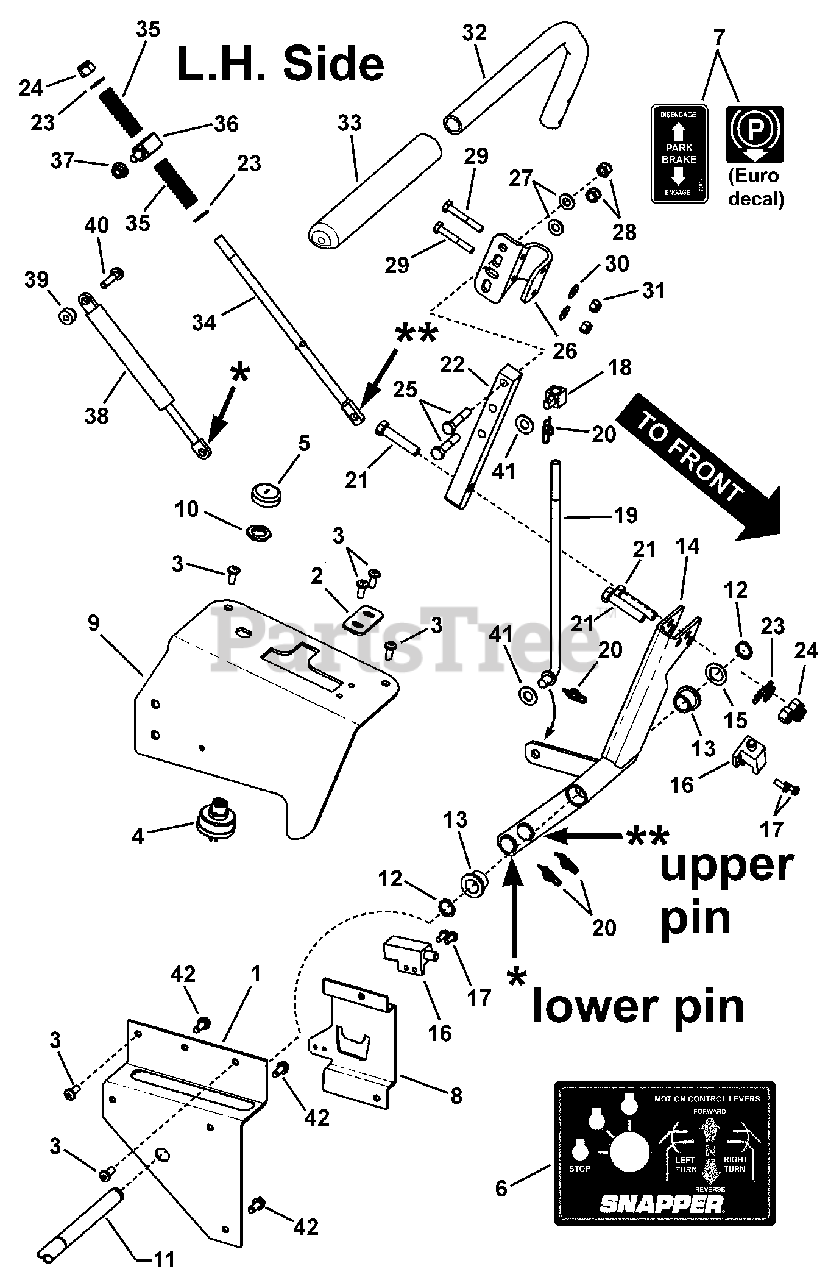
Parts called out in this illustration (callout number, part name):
1	BRACKET, L.H. Tank Support
2	BRACKET, Speed Adjustment
3	SCREW, 1/4-20 x 5/8" Pan Head Self-Tap (Torx)
4	SWITCH, Ignition (After-fire Solenoid)
5	BEZEL
6	DECAL, Ignition Switch
7	DECAL, Park Brake
8	BRACKET, Brake/Clutch Detent, Twin Stick
9	BRACKET, L.H. Console- Twin Stick
10	NUT, 5/8-32 Hex
11	SHAFT, Control, Twin Stick
12	RING, 5/8" External Reatining
13	BUSHING, 5/8 x 5/8" Bronze
14	WELDMENT, Twin Stick, LH
15	WASHER, .64 x .99 x .05 Flat
16	SWITCH, Park Brake (NC/NO)
17	SCREW, #10-24 x 1/2" Hex Washer Self-Tap (Torx)
18	SWIVEL, 3/8-16 Internal Thread
19	CONTROL ROD (3/8-16 thread)
20	COTTER-PIN, 1/16" x 1.42" Self-Locking
21	SCREW, 3/8-16 x 1-3/4" Hex Head Cap, GR 5
22	BLOCK, Twin Stick Control
23	WASHER, 3/8" Flat
24	NUT, 3/8-16 Hex Nyloc
25	SCREW, 5/16-18 x 1-1/2" Hex Head Cap, GR 5
26	BRACKET, Handle Adjustment
27	WASHER, .34 x .69 x .08 Flat
28	NUT, 5/16-18 Hex Nyloc
29	SCREW, 1/4-20 x 1-3/4" Hex Head Cap, GR 5
30	WASHER, .28 x .63 x .06 Flat, GR 5
31	NUT, 1/4-20 Hex Nyloc
32	HANDLE, Twin Stick
33	GRIP, Twin Stick
34	RETURN ROD (3/8-16 thread)
35	SPRING, Neutral Return
36	SWIVEL, Shoulder (5/16-18 thread)
37	NUT, 5/16-18 Hex Flange Lock, GR 5
38	DAMPENER, Hydraulic
39	SPACER, Twin Stick
40	BOLT, 1/4-20 x 1-1/8" Hex Flange Lock, GR 5
41	WASHER, 3/8" SAE Flat
42	SCREW, 1/4-20 x 5/8" Hex Washer Self-Tap
